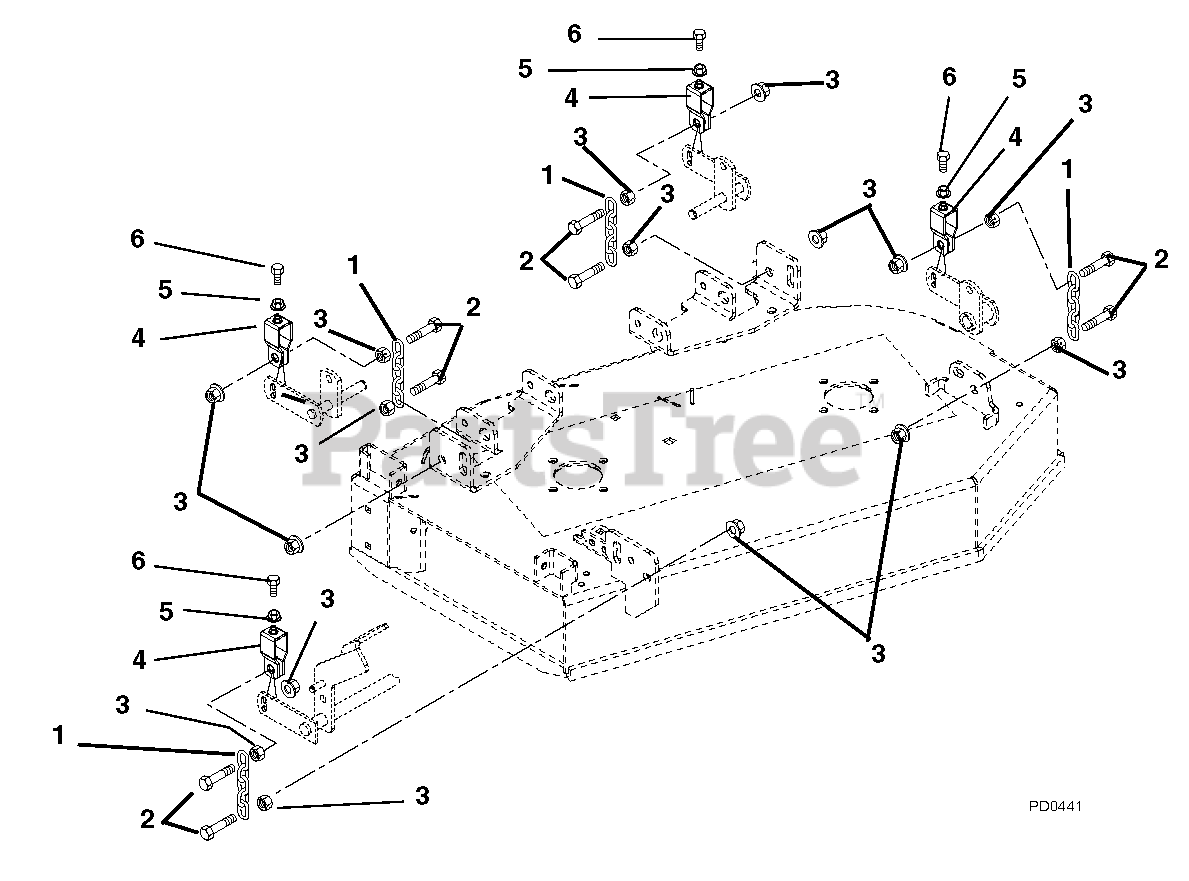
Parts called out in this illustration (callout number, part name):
1	Chain, Link
2	Bolt, Hex M12-1.75 x 50 CLS8.8
3	Nut, Spin Lock-Flange M12-1.75
4	Bracket, Deck Leveling
5	Nut, Jam .312-18
6	Bolt, Hex .312-18 x 2.00 Full Thread Grade 5
